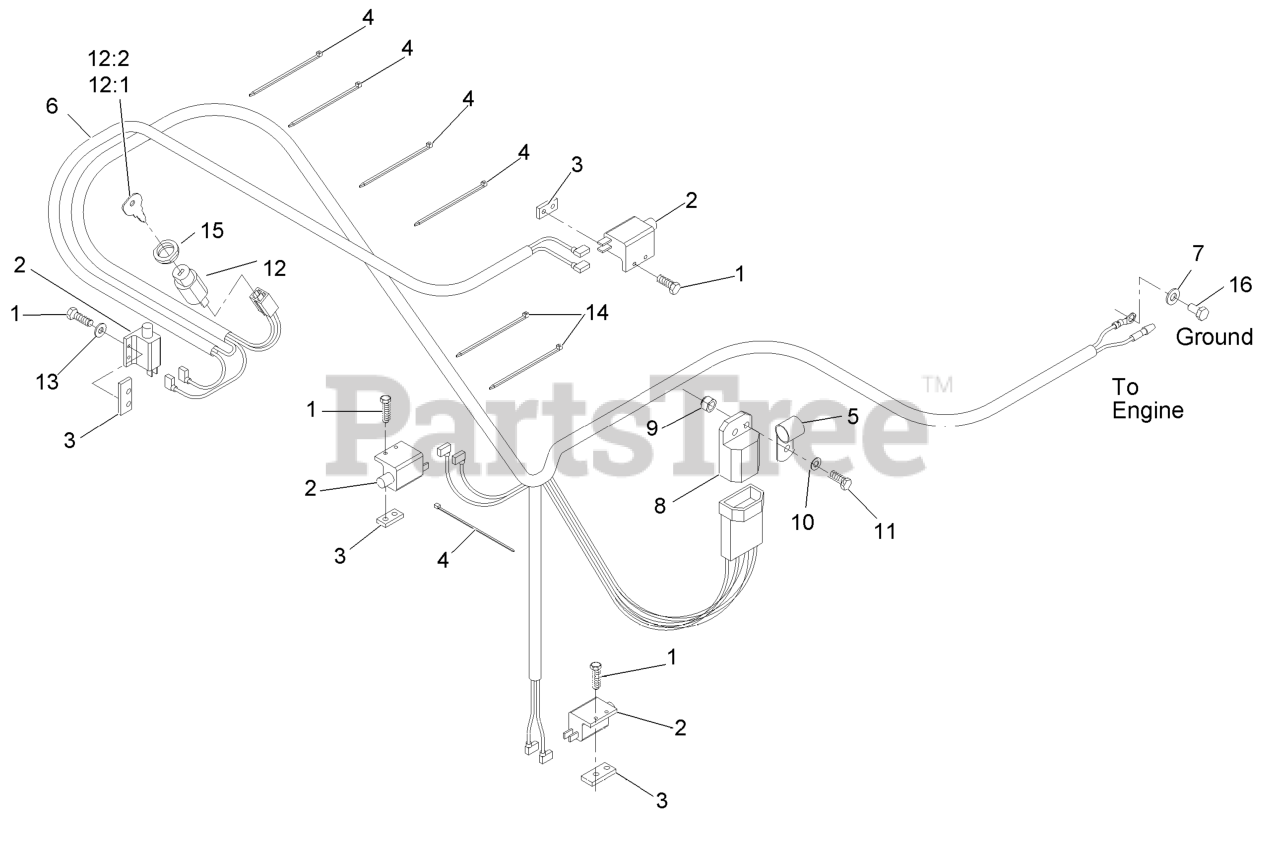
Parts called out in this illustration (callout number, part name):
1	SCREW-PPH
2	SWITCH-OPEN, NORMALLY
3	PLATE-TAPPED
4	TIE-CABLE
5	CLIP-LOOM
6	HARNESS,WIRING KA PULL ST
7	WASHER-PLAIN
8	MODULE-INTERLOCK
9	NUT-LOCK, NI
10	WASHER-FLAT
11	SCREW-HH
12	SWITCH & KEY (INCLUDES NU
12:1	KEYS-IGNITION (SPARE PAIR
12:2	KEY-IGNITION
13	WASHER-FLAT
14	TIE-PLASTIC
15	NUT-SWITCH, IGNITION
16	SCREW-HH
